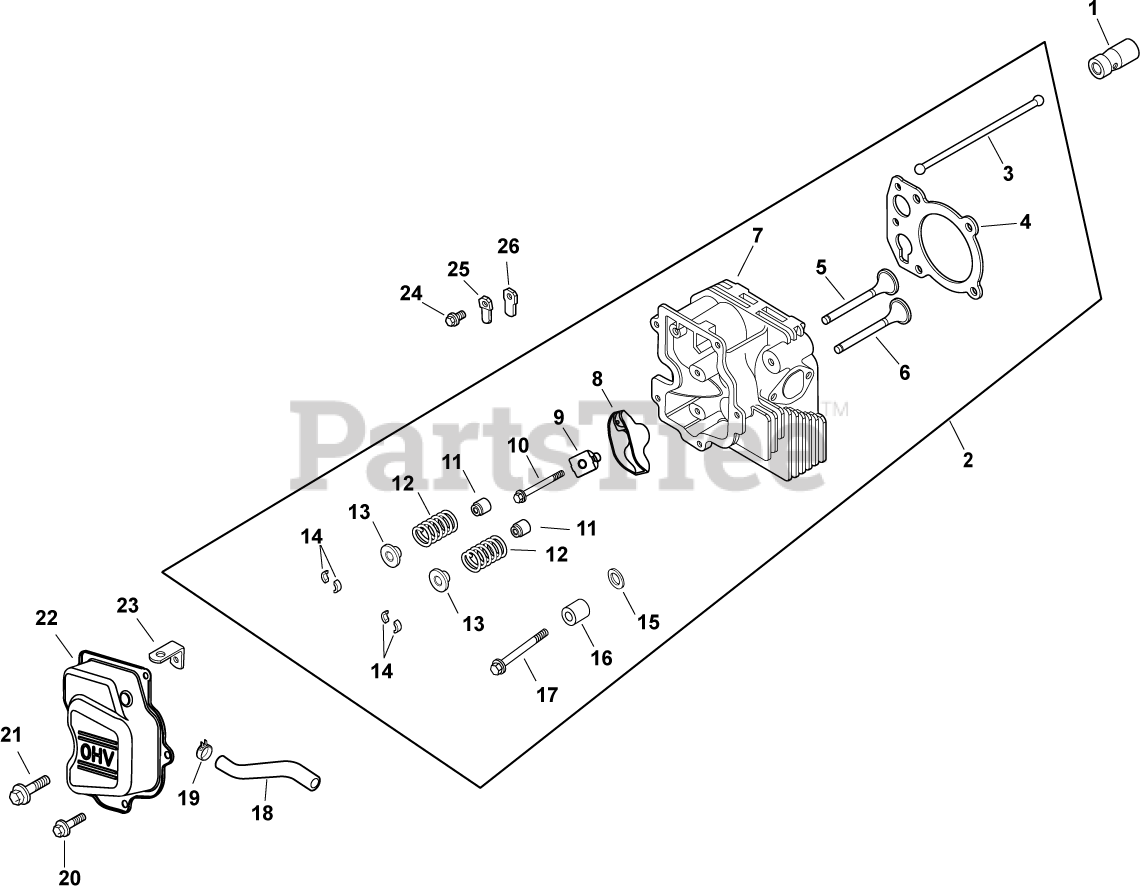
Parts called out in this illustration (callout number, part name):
1	LIFTER, HYDRAULIC VALVE-USE 25 351 10-S
2	KIT, CYLINDER HEAD
3	ROD, PUSH
4	GASKET, CYLINDER HEAD
5	VALVE, EXHAUST
6	VALVE, INTAKE
7	KIT, HEAD, CYLINDER
8	ARM, ROCKER
9	PIVOT, ROCKER ARM
10	SCREW, FLG M6X1.0X34
11	SEAL, VALVE STEM - (#2503214S)
12	SPRING, VALVE
13	RETAINER, VALVE SPRING - USE 25 173 28-S
14	KIT, RETAINER
15	WASHER, FLAT 13/32"
16	SPACER, HEAD BOLT EXHAUST PORT
17	SCREW, CYLINDER HEAD (M10 X 80)
18	HOSE, BREATHER
19	CLAMP, HOSE (KM)-USE 25 237 31-S
20	SCREW,FLG THD FRM M6X1.0X16-(#25086397S)
21	SCREW,FLG THD FRM M6X1.0X20-(#25086396S)
22	COVER, ROCKER
24	SCREW, FLG THD FRM M5X.8X10
25	RETAINER, REED
26	REED, BREATHER
